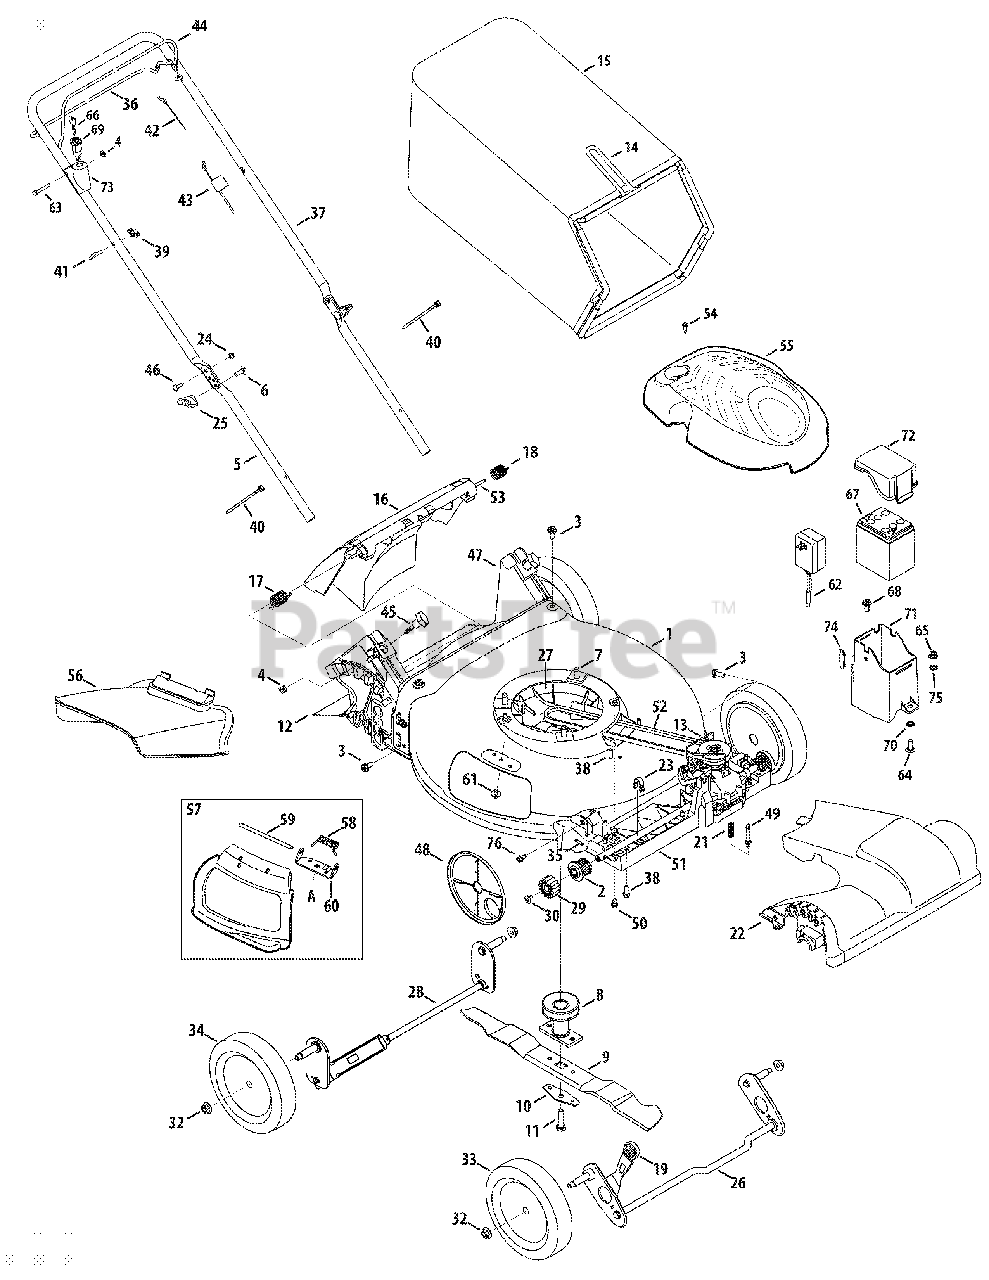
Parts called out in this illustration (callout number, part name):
1	Deck , 21"
1	Deck, 21" (Honda)
2	Bearing Assembly
3	Screw, 5/16-14 x .750
4	Nut, Sq., 1/4-20
5	Lower Handle
6	Carriage Screw ,5/16-18
7	Screw, 3/8-16 x 1.00
8	Blade Adapter
8	Blade Adapter (Honda)
9	Mulching Blade
10	Blade Bell Support
11	Screw, 3/8-24 x 1.50
12	Trailing Shield
13	Transmission Wire
14	Grass Catcher Frame
15	Grass Bag
16	Rear Discharge Door Assembly
17	Torsion Spring - RH
18	Torsion Spring - LH
19	Adjustment Lever Knob
20	Screw, 1/4-20 x .500
21	Compression Spring
22	Front Cover
23	Front Axle Clip
24	Nut, Flange Lock, 1/4-20
25	Wing Knob
26	Front Axle Assembly
27	Engine Baffle
28	Rear Axle Assembly
29	Spur Gear, 14T - RH
29	Spur Gear, 14T - LH
30	Screw, 1/4-20 x .390
32	Flange Lock Nut, 3/8-16
33	Front Wheel
34	Rear Wheel
35	Dowel Pin
36	Drive Control
37	Upper Handle
38	Screw, 1/4-15 x .750
40	Cable Tie
40	Guide, Cable
41	Rope Guide
42	Control Cable
42	Control Cable (Honda)
43	Drive Cable
44	Blade Control
45	Wing Nut
46	Sldr. Screw, .375 x .126 x 1/4-20
47	Washer, Bell, .340 x .872 x .080
48	Wheel Dust Cover
49	Spring Body
50	Scr., Shldr., 1/4-20 x .50
51	Lower Tray
53	Pivot Rod
54	Screw, #12-16 x 1.00
55	Engine Shroud
56	Side Discharge Chute
57	Mulch Plug (Incl. 58-60)
58	Torsion Spring
59	Hinge Pin
60	Chute Deflector Bracket
61	Screw, 1/4-20 x .500
62	Battery Charger
63	Screw, 1/4-20 x 1.75
64	Bolt, Carr., 5/16-18 x 1.00
65	Nut, Hexlk, 5/16-18
66	Key
67	Battery
68	Screw., Sldr., 5/16-14 x .972
69	Key Switch
70	Speed Nut
71	Battery Housing
72	Battery Housing Top
73	Electric Start Housing
74	Lid Seal
75	Washer, Bell, .340 x .872 x .080
76	Screw., Sldr., 1/4-20 x .70
